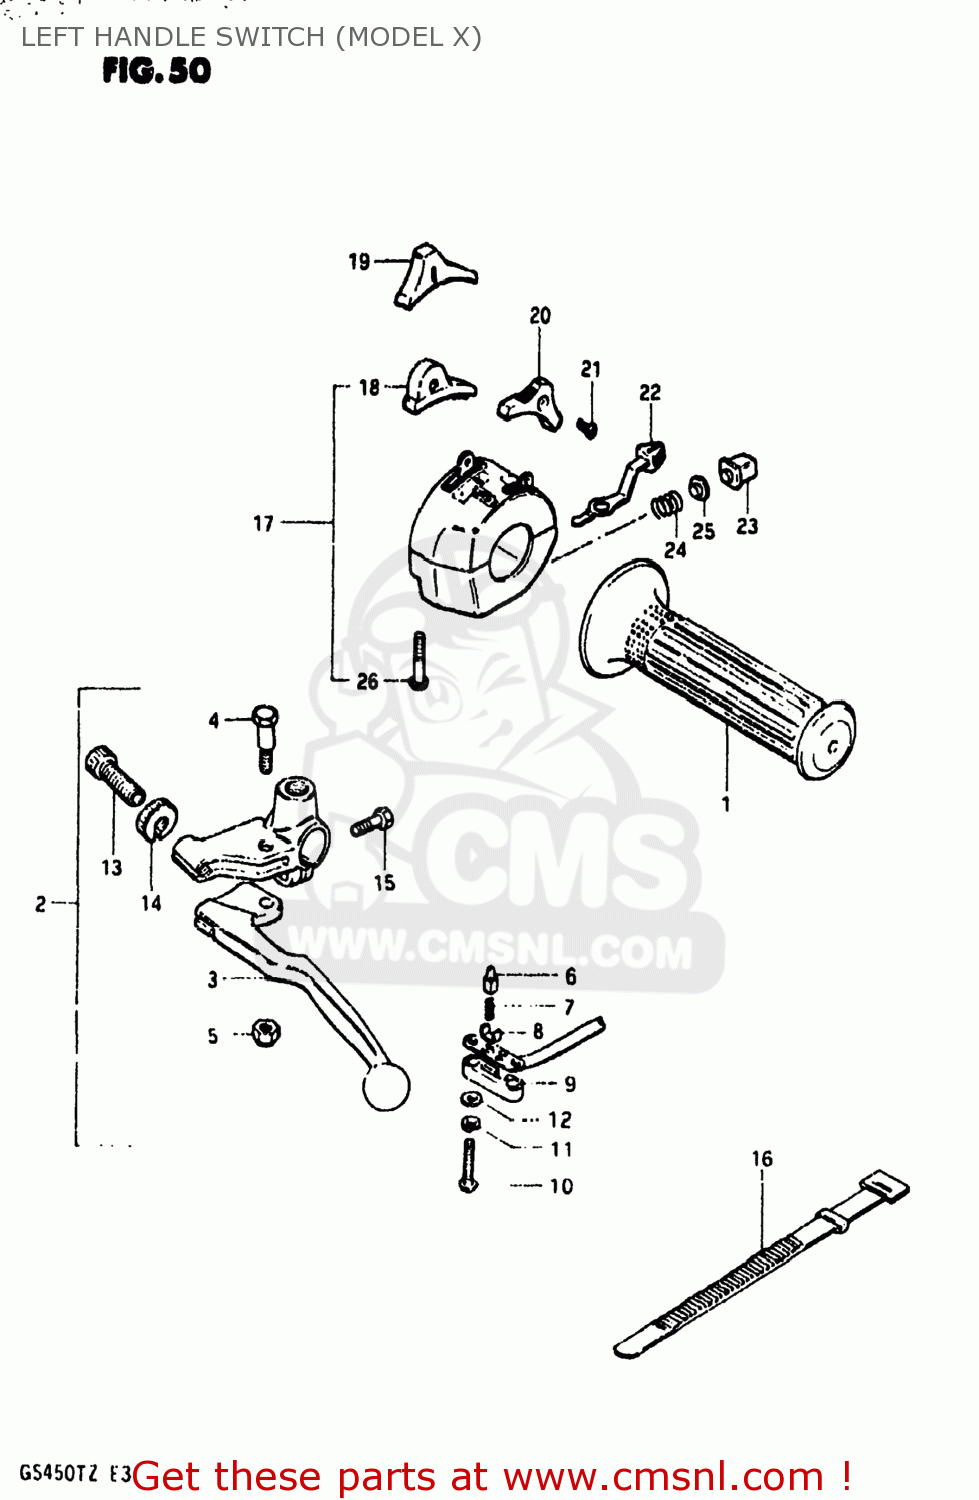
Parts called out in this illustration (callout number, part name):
1	GRIP,LEFT
2	LEVER ASSEMBLY
3	LEVER,CLUTCH
4	BOLT,LEVER
5	NUT 6MM
6	HOLDER
7	SPRING
8	PLATE
9	COVER,FR BK TERMINAL BASE
10	SCREW
11	LOCK WASHER
12	WASHER
13	ADJUSTER,CABLE
14	NUT,CABLE ADJUSTER
15	BOLT,CLUTCH LEVER HOLDER
16	CLAMP(L:120)
17	SWITCH ASSY,HANDLE,L
18	KNOB,STOP
19	KNOB,LIGHTING SWITCH
20	KNOB,DIMMER SWITCH
21	SCREW
22	KNOB,TURNSIGNAL
23	BUTTON,HORN
24	SPRING
25	CONTACT
26	SCREW
